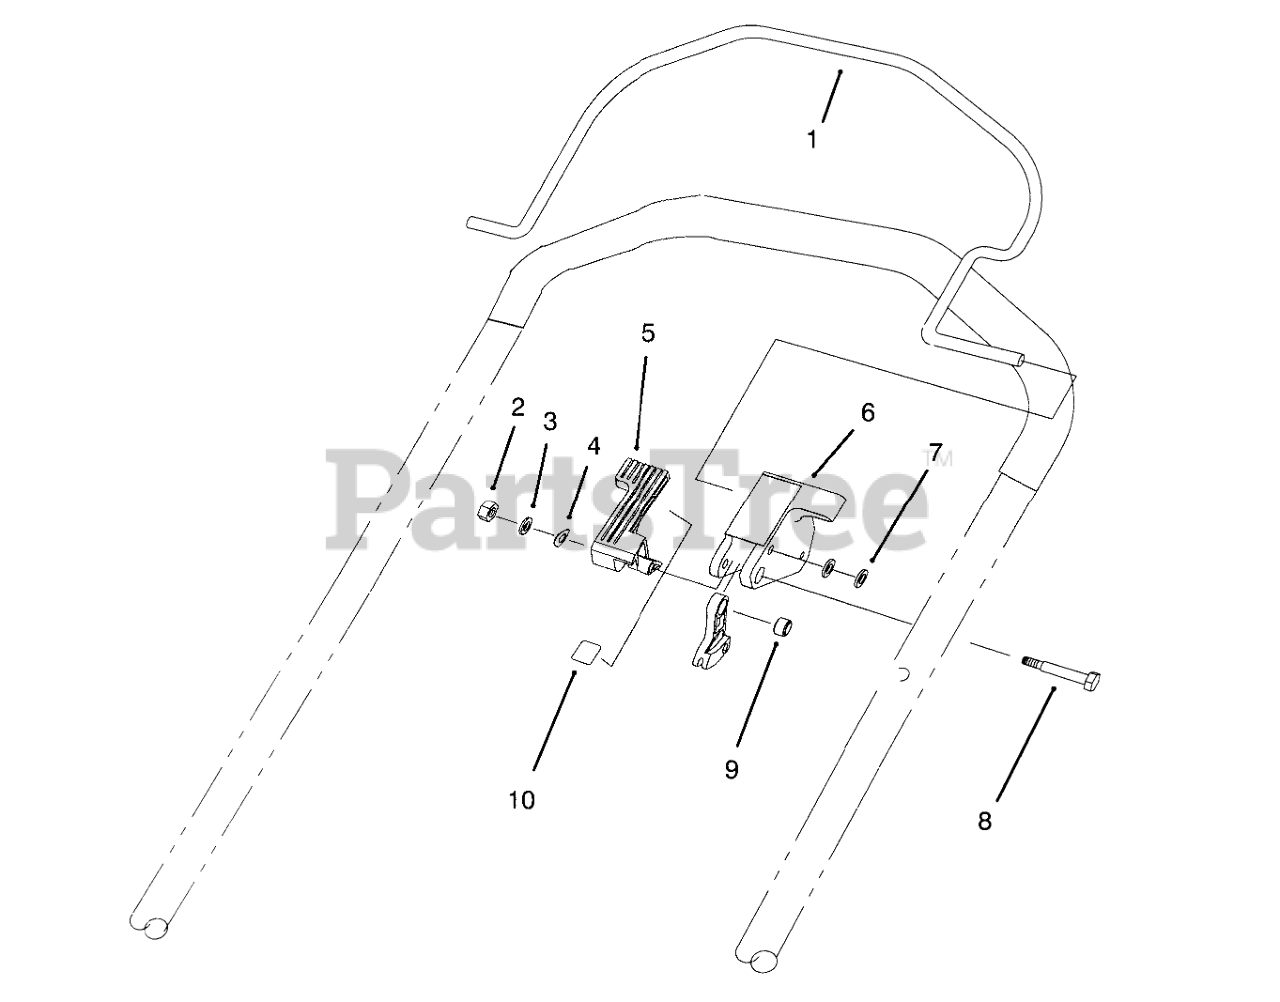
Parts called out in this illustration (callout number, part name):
1	BAIL - CONTROL
2	NUT-LOCK, NI
3	WASHER-PLAIN
4	WASHER - SPRING
5	LEVER - SHIFT
6	STOP - PIVOT, PLASTIC
7	WASHER-FLAT
8	SHOULDER BOLT
9	SPACER-LEVER, TRACTION
10	DECAL - TRACTION
